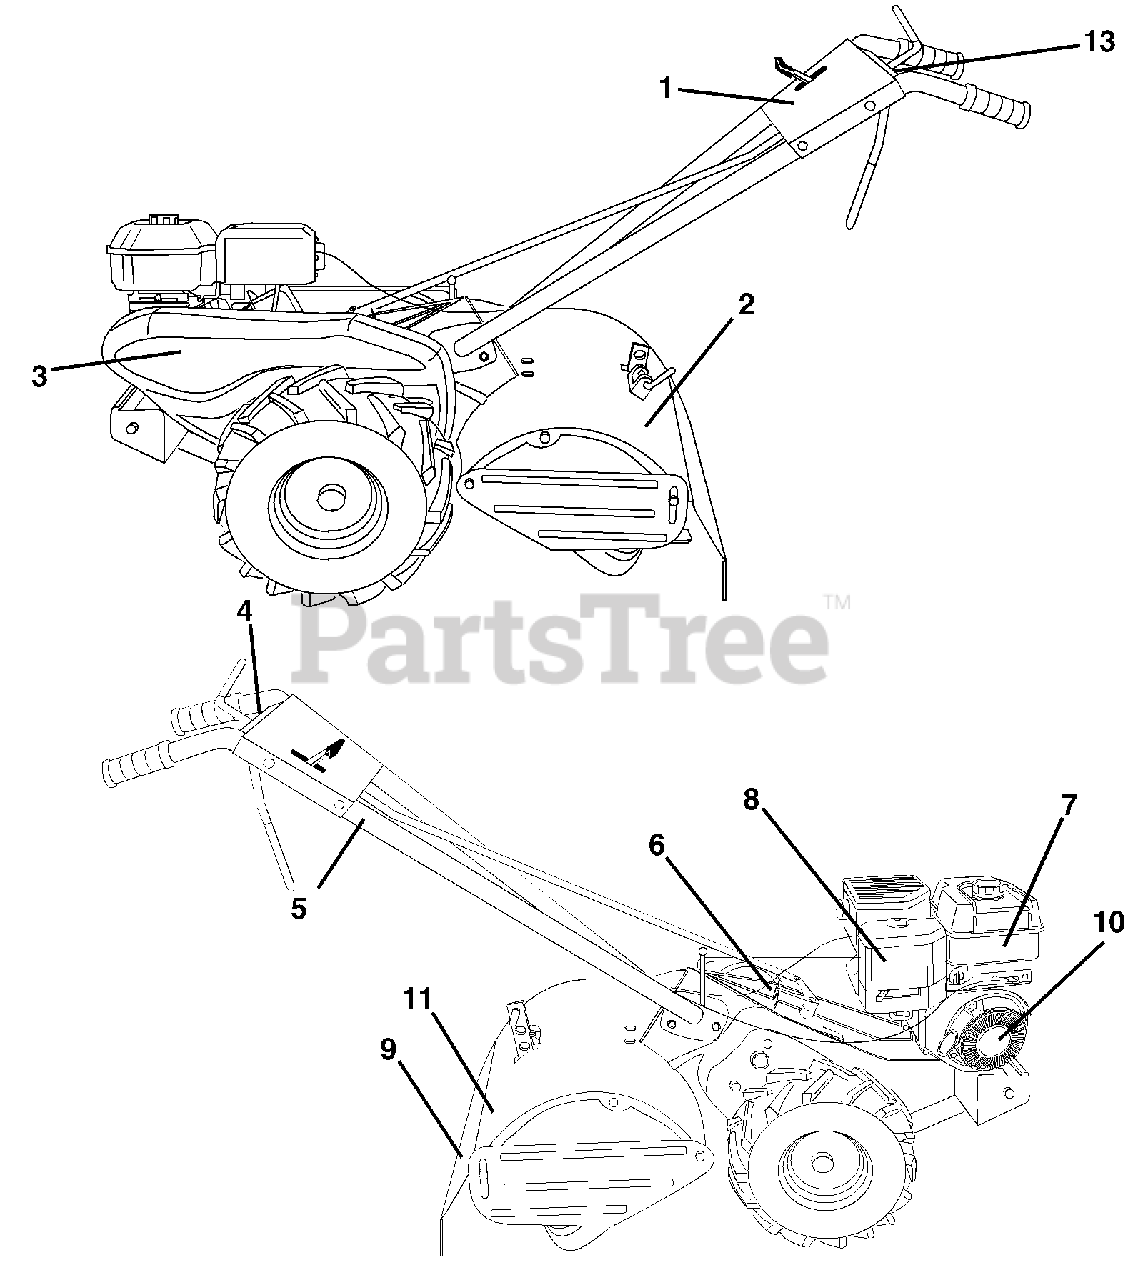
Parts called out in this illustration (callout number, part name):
1	Decal, Control Panel
2	Decal, Warning
3	Decal, Belt Guard
4	Decal, Instruction, Tilling
5	Decal, Hand Placement
6	Decal, Shift Indicator
7	Decal, OHV N-I/C 190CELBL
8	Decal, Briggs & Stratton
9	Decal, Warning
10	Decal, Rewind INTEK
11	Decal, Tine Shield
13	Decal, Control Panel Reverse
